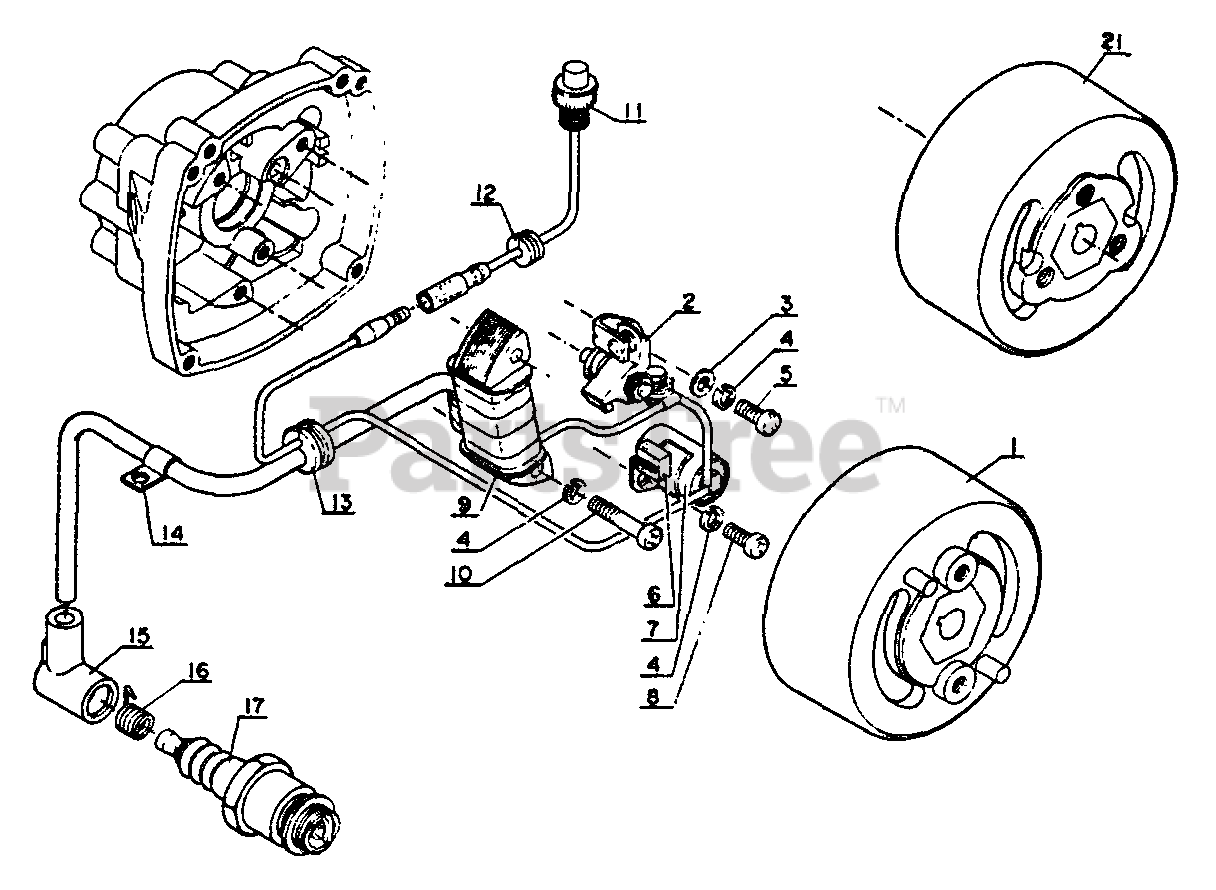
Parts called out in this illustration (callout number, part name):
1	FLYWHEEL
2	CONTACT POINT SET
3	WASHER 4 MM
4	WASHER, SPRING 4 MM
5	SCREW - 4×8
7	CONDENSER
8	SCREW - 4×8
9	COIL, IGNITION
10	SCREW - 4×20
11	BUTTON, STOP
12	GROMMET
14	CLAMP
15	CAP, SPARK PLUG
16	TERMINAL, SPARK PLUG CAP
17	SPARK PLUG - BM6A
21	FLYWHEEL
